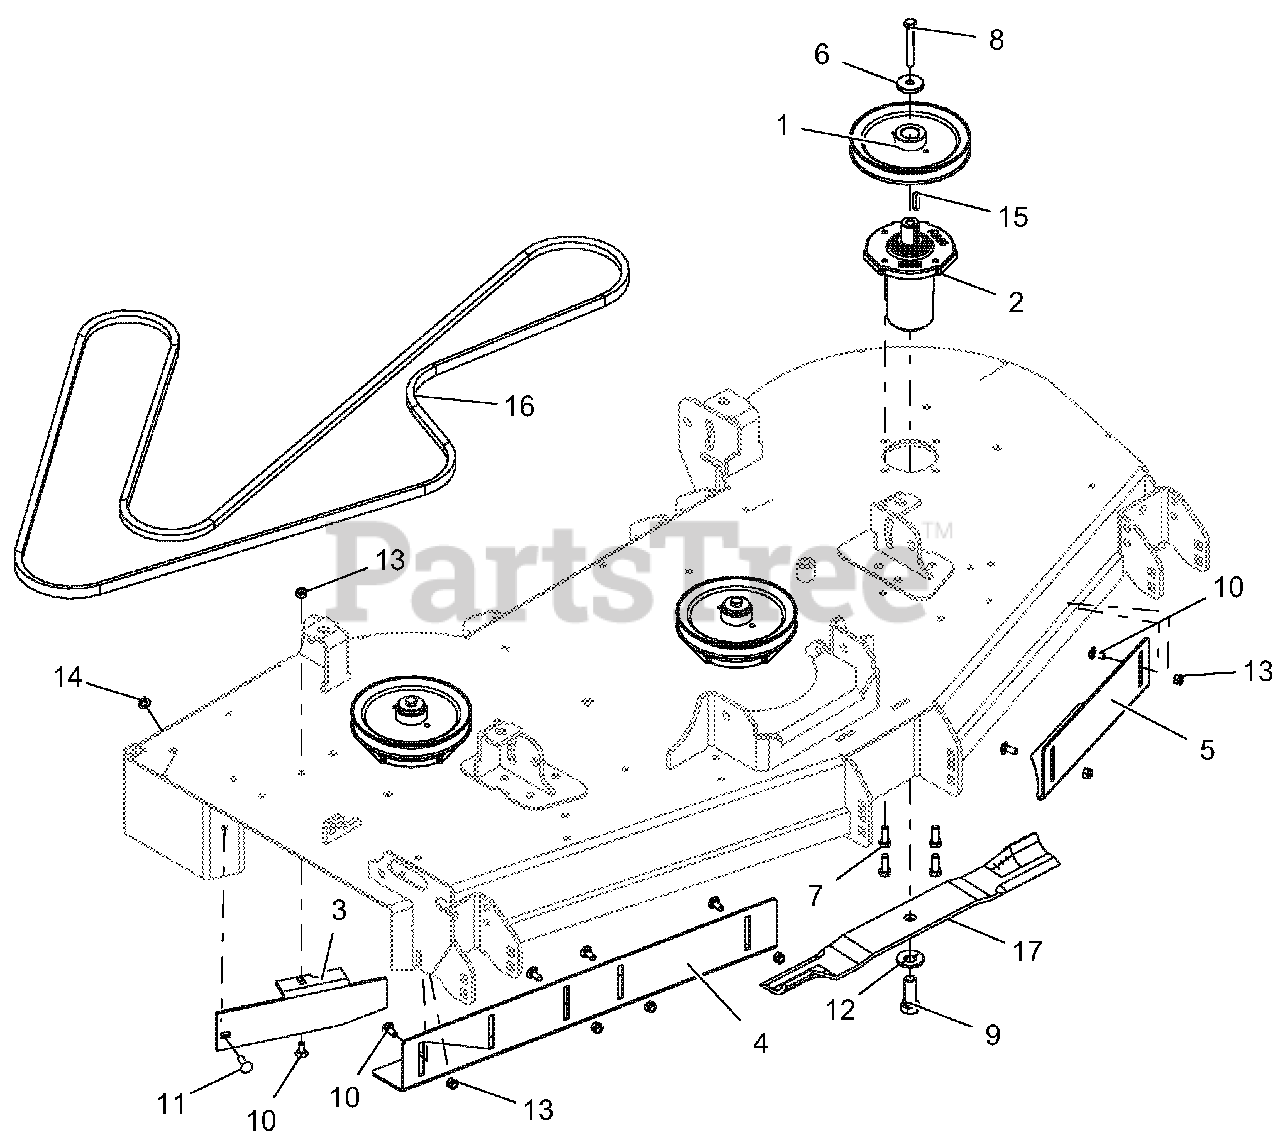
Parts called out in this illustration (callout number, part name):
1	PULLEY, V-1.00 ID X 6.75 OD
2	SERVICE, ASM SPINDLE- DUCTILE
3	BAFFLE, 60" DISCHARGE
4	BAFFLE, 60" RH VACUUM
5	BAFFLE, 60" LH VACUUM
6	RETAINER, SHEAVE SPINDLE
7	BLT-HEX .38-16X1.00 GR5 YWZC EP30
8	BLT-HEX .38-16X2.75 GR8 YWZC
9	BLT, HEX .62-18X1.75 GR8 YWZC
10	BLT-RDHDSQNK .31-18X.75 G5 YWZC
11	BLT-RDHDSQSHNK .31-18X1.00 G5 Y
12	WSHR, BLVL .63X1.625X.14
13	NUT-LK-NYL .312-18 YWZC
14	NUT-LK-NYL-FLG .31-18 YWZC
15	KEY-SQ .250X.250X1.00 RC 40-50
16	V-BELT, B SECTION RAW EDGE
17	BLADE, MOWER 60"
